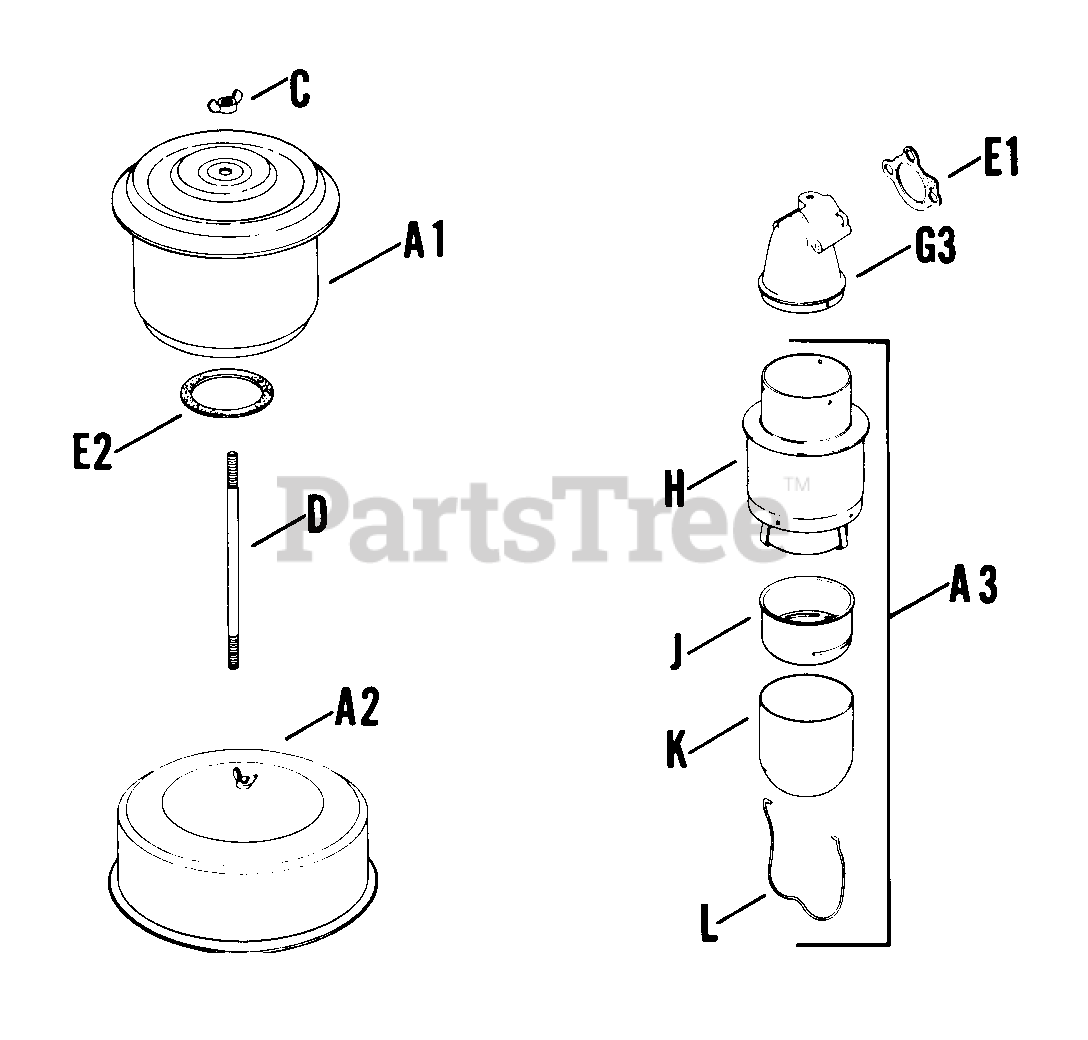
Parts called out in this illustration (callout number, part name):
G3	ELBOW - DISCONTINUED
K	CUP - DISCONTINUED
L	FASTENER - DISCONTINUED
